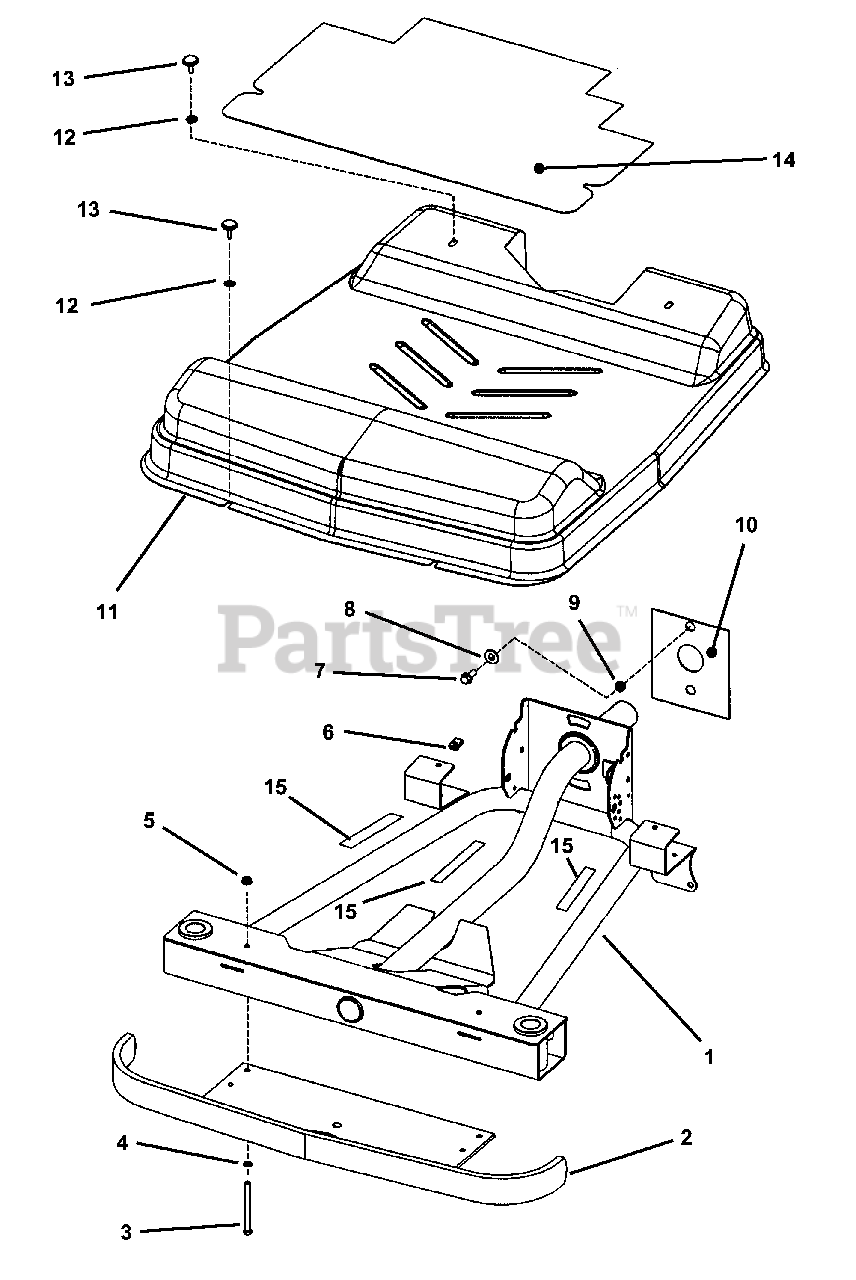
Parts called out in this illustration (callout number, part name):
1	FRAME, Front
2	BUMPER, Front
3	BOLT, 5/16-18 x 3-3/4"
4	WASHER, 5/16" Split Lock
5	NUT, 5/16-18 Hex Flange Lock, Grade 5
6	FASTENER, "U" Type 1/4"-20
7	SCREW, 3/8-16 x 1" Hex Washer Face, Self-Tap
8	WASHER, 3/8" Flat (was 90517)
9	SPACER, Front Frame Pivot
10	PLATE, Front Frame Pivot
11	FLOOR, Front Frame
12	WASHER, 1/4" Internal/External Lock
14	FLOOR MAT
15	PAD, Floor Pan
